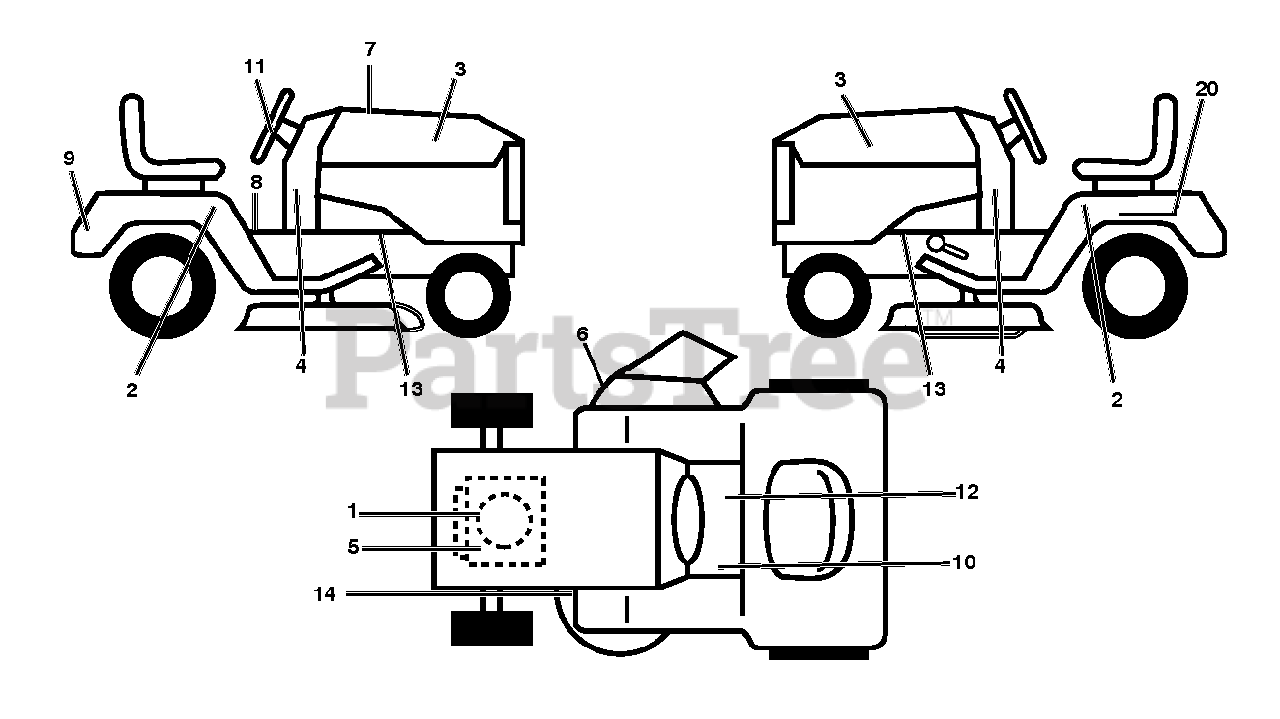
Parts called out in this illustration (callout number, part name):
3	DECAL.HOOD.ALPHA.RH/LH.POULAN
6	DECAL.WARN.DFLECT/CTFINGR.SRD
9	DECAL.FEND.POULAN.2010
11	DECAL.WHEEL.STRG.STDHRS.POULAN
12	DECAL PARK BRAKE
20	DECAL BTRY SYMBOLS
